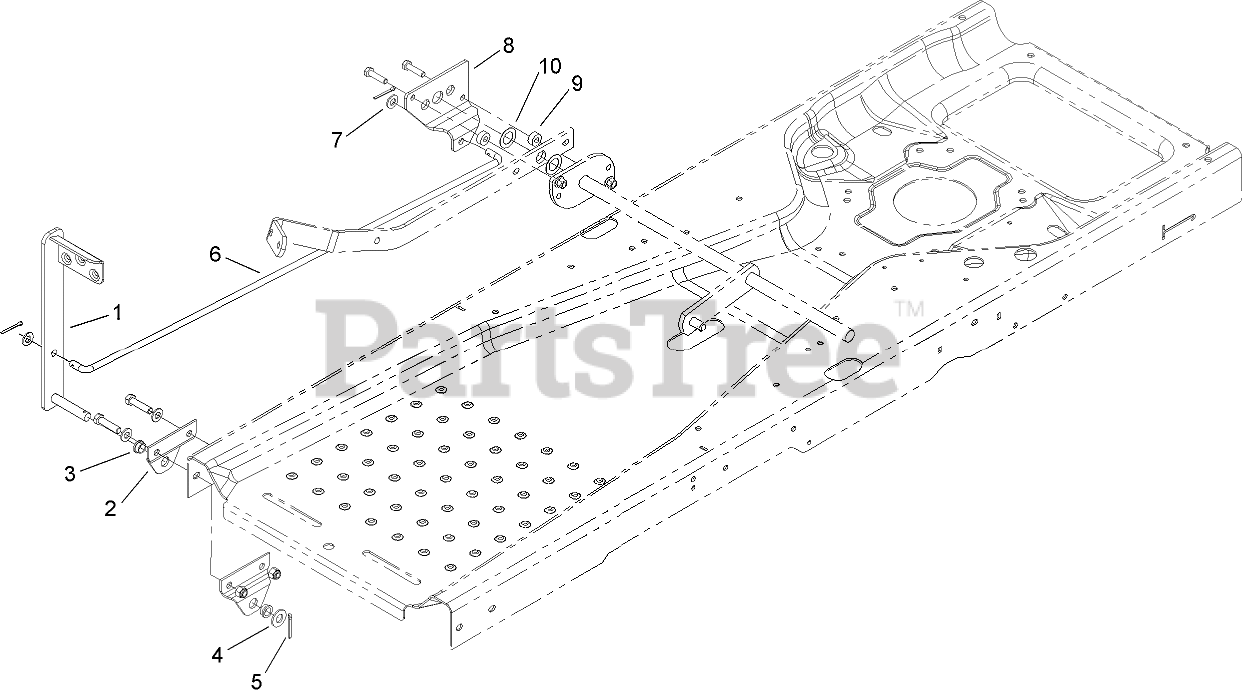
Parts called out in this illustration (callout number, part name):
1	PEDAL ASM
2	BRACKET-FOOTLIFT
3	BUSHING-FLANGE
4	WASHER-FLAT
5	PIN-COTTER
6	ROD-LIFT
7	WASHER-FLAT
8	PLATE-FOOTLIFT
9	SPACER
10	WASHER-THRUST
